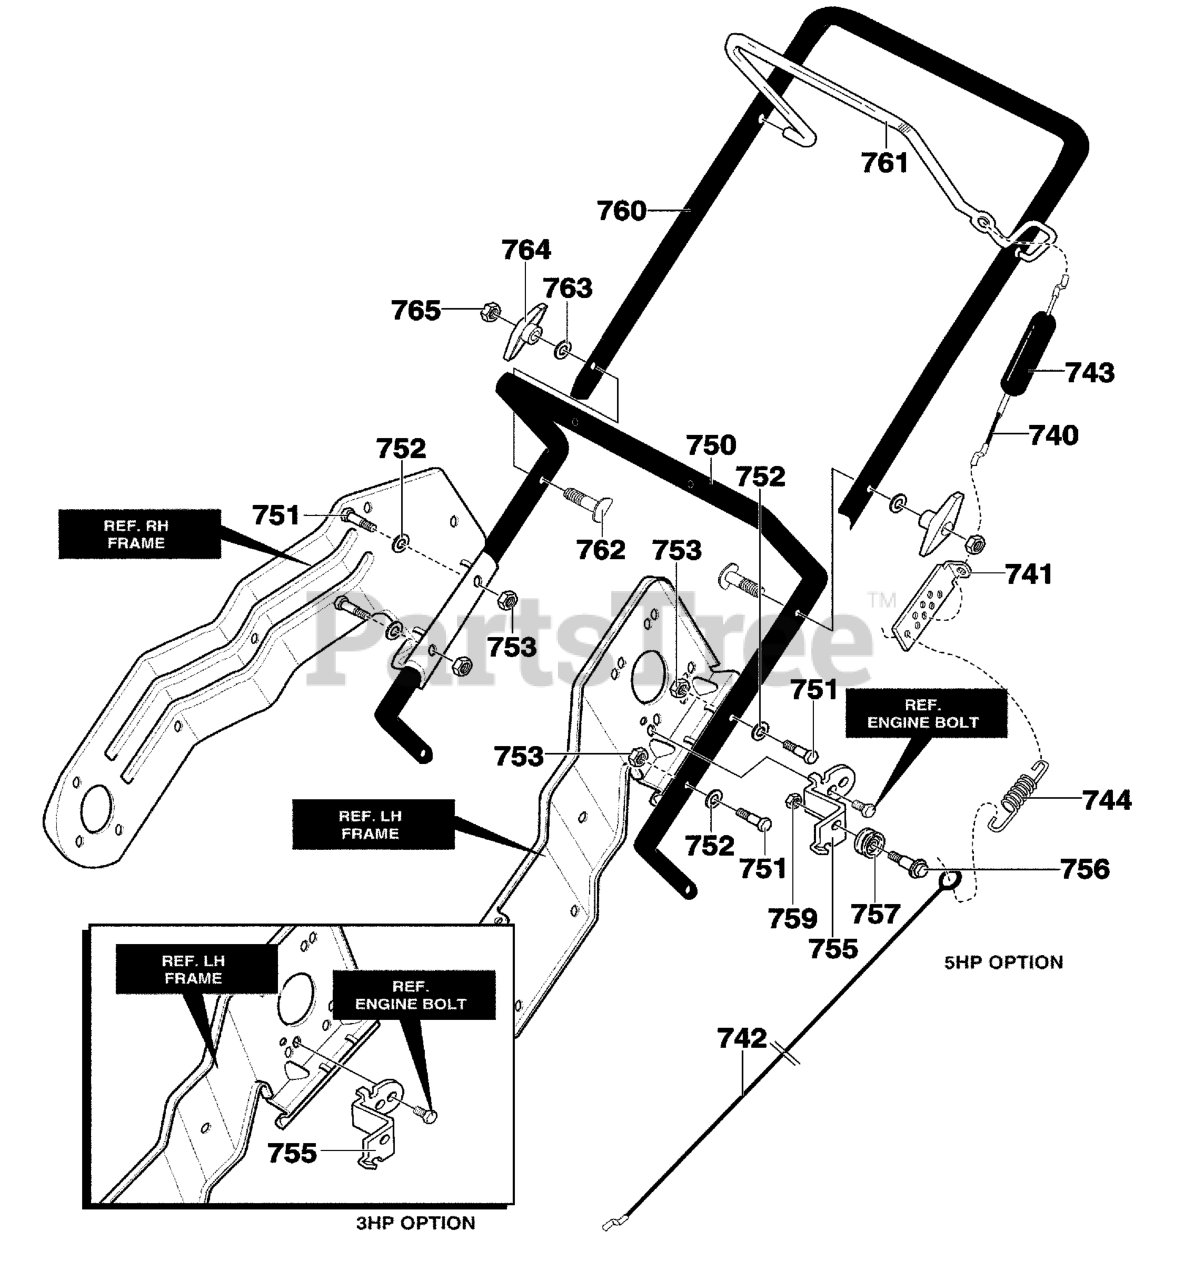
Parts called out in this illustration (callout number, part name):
740	CABLE, UPPER
741	BRKT, CABLE ADJ
742	CABLE LOWER CONTROL
743	BOOT, CLUTCH SPRING
750	HANDLE LOWER
751	SCREW, 1/4-20X1.25
752	WASHER, FLAT .281X.63X.065
753	NUT, 1/4-20
755	BRACKET, CABLE
756	BOLT, .375X.375 1/4-20
757	PULLEY, .906X.305
759	NUT, 1/4-20
760	HANDLE, UPPER
761	BAIL, CONTROL
762	BOLT, 5/16-18X2.00
763	WASHER, FORM
764	KNOB,T
765	NUT, 5/16-18
